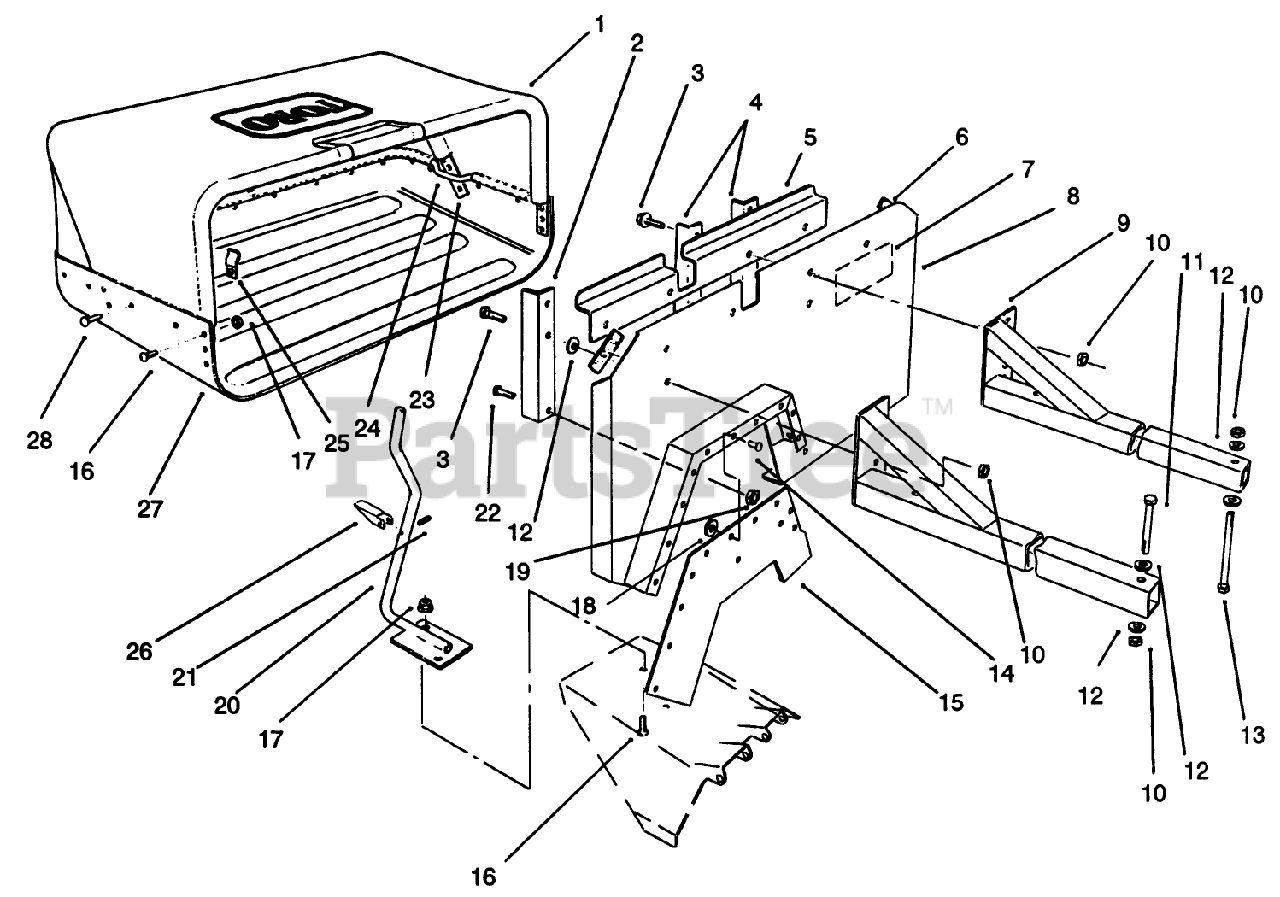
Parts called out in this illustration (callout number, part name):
1	Bag-Cloth
2	Support-Panel, RH
3	SCREW-HHF
4	Support-Panel
5	Support-Bag
6	PAD-RUBBER
7	DECAL-DANGER
8	Panel-Back
9	Mount-Beam
10	NUT-HHF, WHIZ
11	SCREW-HH
12	WASHER-FLAT
13	SCREW-HH
14	RIVET-POP
15	Extension-Rubber
16	SCREW-PPH
17	NUT-HF
18	WASHER-PLAIN
19	NUT-HF
20	Rod-Lockup
21	PIN-SPRING
23	Tube-Bag Support
24	Rod-Cloth
25	CLIP-HALF
26	LATCH-LOCKUP
27	TRAY-BAG, GRASS
28	RIVET-BLIND
